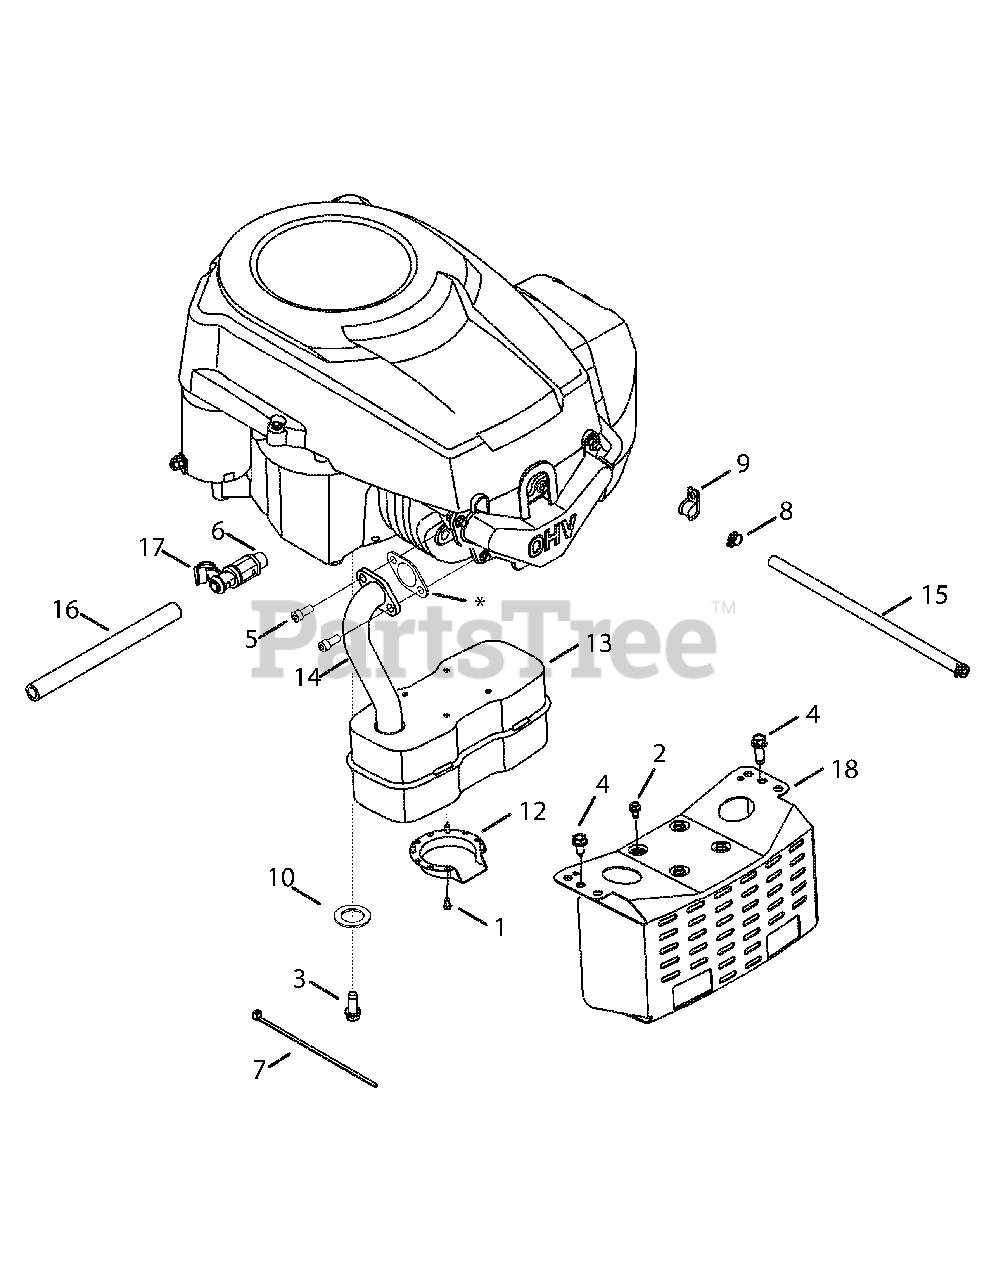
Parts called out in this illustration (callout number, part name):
1	Hex AB Scr #8-18 x .50
2	Hex Wash S-Tapp Scr 1/4-20 x .50
3	TT Screw 3/8-16 x 1.00
4	S-Tapp Scr 5/16-18 x .75
5	Scr. 5/16-18 x .75
6	Loctite 567 Sealant
10	Flat Washer 1.031 x 1.620 x .095
12	Muffler Deflector
13	Muffler
15	Fuel Line
16	Oil Drain Hose
17	Oil Drain Cap
